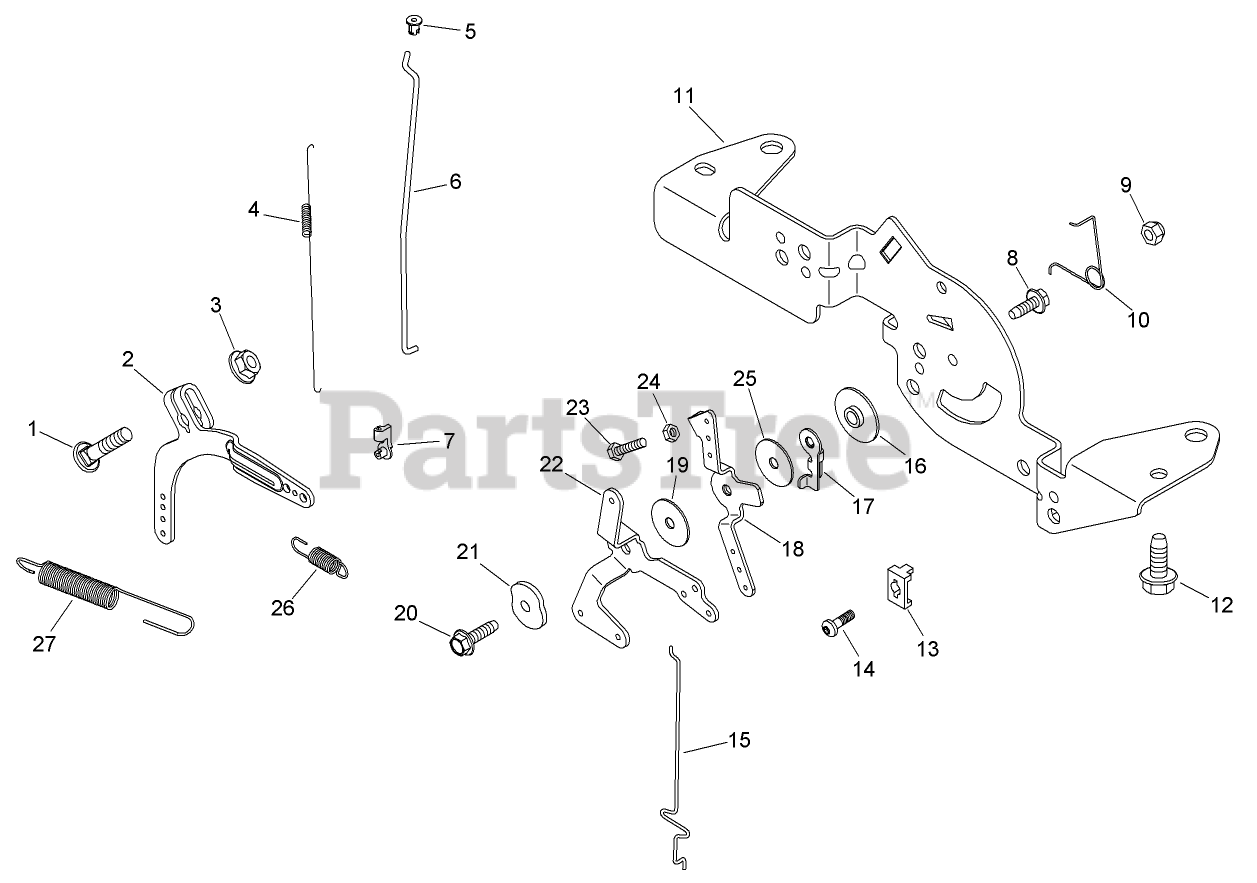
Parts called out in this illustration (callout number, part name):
1	BOLT-SQ NECK, RD HD (M6X1.0X25)
2	LEVER-GOVERNOR
3	NUT-FLANGE (M6X1.0)
4	SPRING-LINKAGE
5	BUSHING-LINKAGE, THROTTLE
6	LINKAGE-THROTTLE
7	BUSHING-RETAINING, LINKAGE
8	SCREW-FLANGE, THREAD FORMING (M5X0.8X16)
9	NUT-LOCK (M5X.8)
10	SPRING-RETURN, CHOKE
11	BRACKET-CONTROL
12	SCREW-FLANGE, THREAD FORMING (M6X1.0X16)
13	CLAMP-CABLE
14	SCREW-LBD, THD FRM (M5X0.8X16)
15	LINKAGE-CHOKE
16	CONTROL SPACER ASM
17	LEVER-ACTUATOR, THROTTLE
18	LEVER-CONTROL, THROTTLE
19	WASHER-FLAT (5.5MM)
20	SCREW-FLANGE, THREAD FORMING (M5X.8X20)
21	WASHER-SPRING (1/4)
22	LEVER-CHOKE
23	SCREW-SLOTTED HEAD (M4X0.7X25)
24	NUT (M4X0.7)
25	WASHER-FLAT (5MM)
26	SPRING-GOVERNOR
27	SPRING-GOVERNOR
